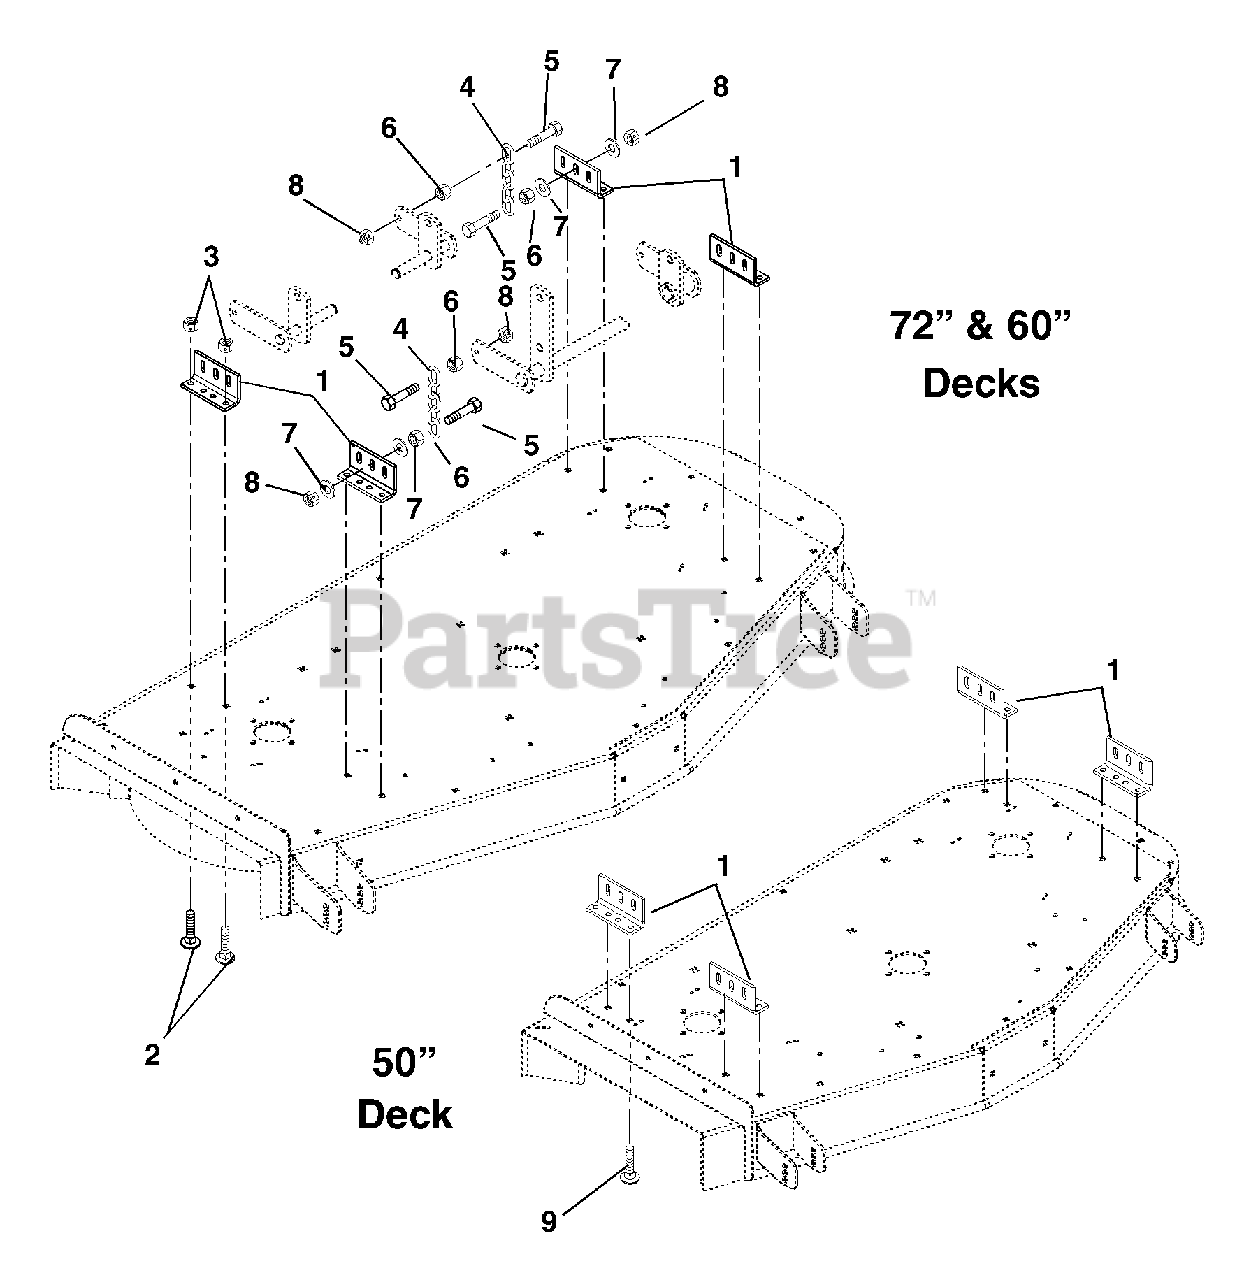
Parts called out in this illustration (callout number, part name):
1	Bracket, Mower Mounting
2	Bolt-Round Head Square Neck .38-16 x 1.25 Grade 2 (60" Deck)
2	Bolt-Round Head Square Neck .38-16 x 1.25 Grade 2 (50" Deck)
3	Nut-Locking-Nylon .38-16
4	Chain, Link
5	Bolt-Hex .38-16 x 1.50 Grade 5
6	Nut-Hex .38-16
7	Washer-Flat-Steel .406 x .812 x .065
8	Nut-Locking-Center .38-16
9	Bolt-Round Head Square Neck .38-16 x 1.50 Grade 2 (50" Deck)
